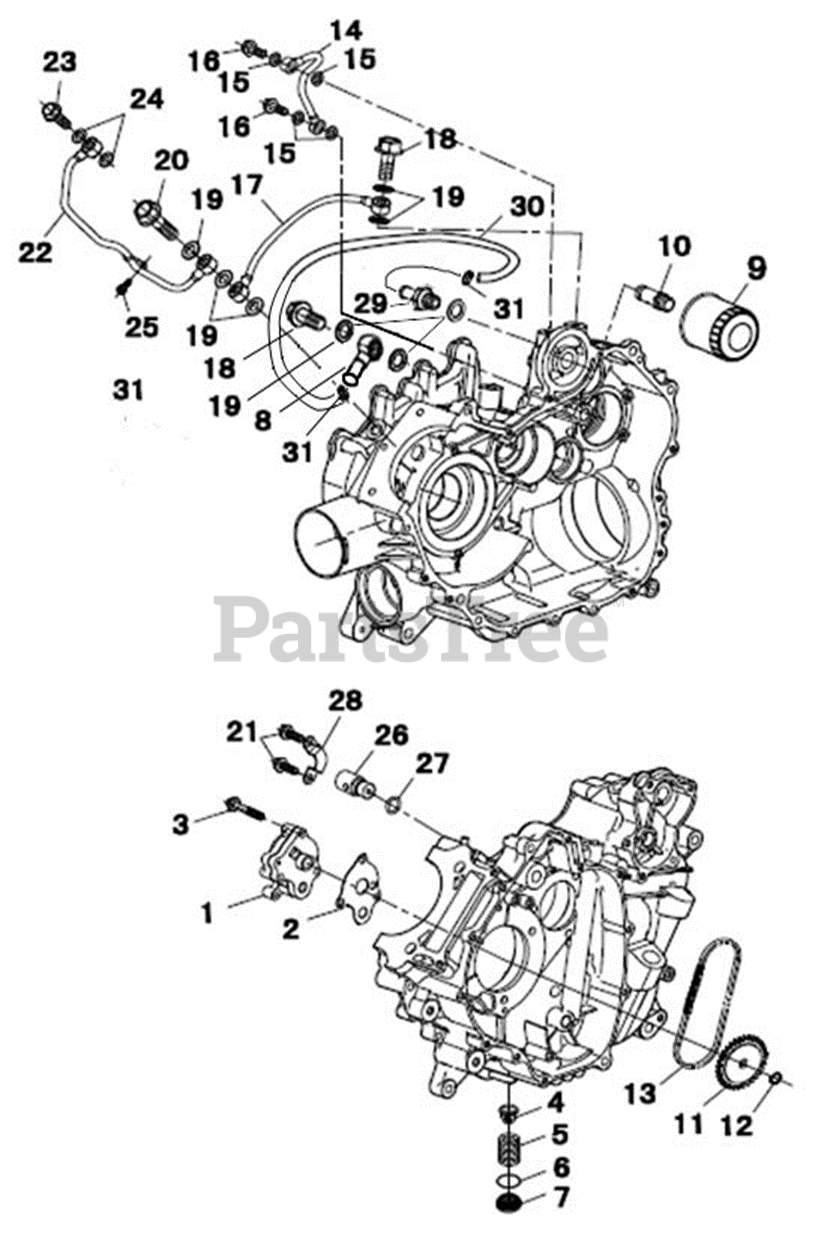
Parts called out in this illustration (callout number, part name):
1	OIL PUMP ASSEMBLY
2	OIL PUMP GASKET
3	HEX FLANGE BOLTS M6X40
4	OIL FILTER STRAINER
5	FILTER SPRING
6	O-RING 36X3.5
7	OIL DRAIN NUT
8	BANJO BOLT
9	OIL FILTER
10	FILTER JOINT
11	OIL PUMP DRIVEN SPROCKET
13	OIL PUMP CHAIN
14	OIL TUBE WELDING ASSEMBLY A
15	ALUMINUM WASHER 8X15X2
16	BOLT FOR OIL TUBE M8X25
17	OIL TUBE WELDING ASSEMBLY B
18	BOLT FOR OIL TUBE M14X1.5X28
19	ALUMINUM WASHER 14X22X1.5
20	BOLT FOR OIL TUBE M14X1.5X50
21	HEX FLANGE BOLT M6X14
22	OIL TUBE WELDING ASSEMBLY C
23	BOLT FOR OIL TUBE M10X1.25X30
24	ALUMINUM WASHER 10X16X1.2
25	HEX FLANGE BOLT M6X12
26	PRESSURE REGULATING VALVE ASM
27	O-RING 10X2.45
28	PRESSURE REGULATING VALVE PLATE
29	OIL PIPE JOINT
30	RUBBER HOSE
31	HOSE CLAMP ASSEMBLY
